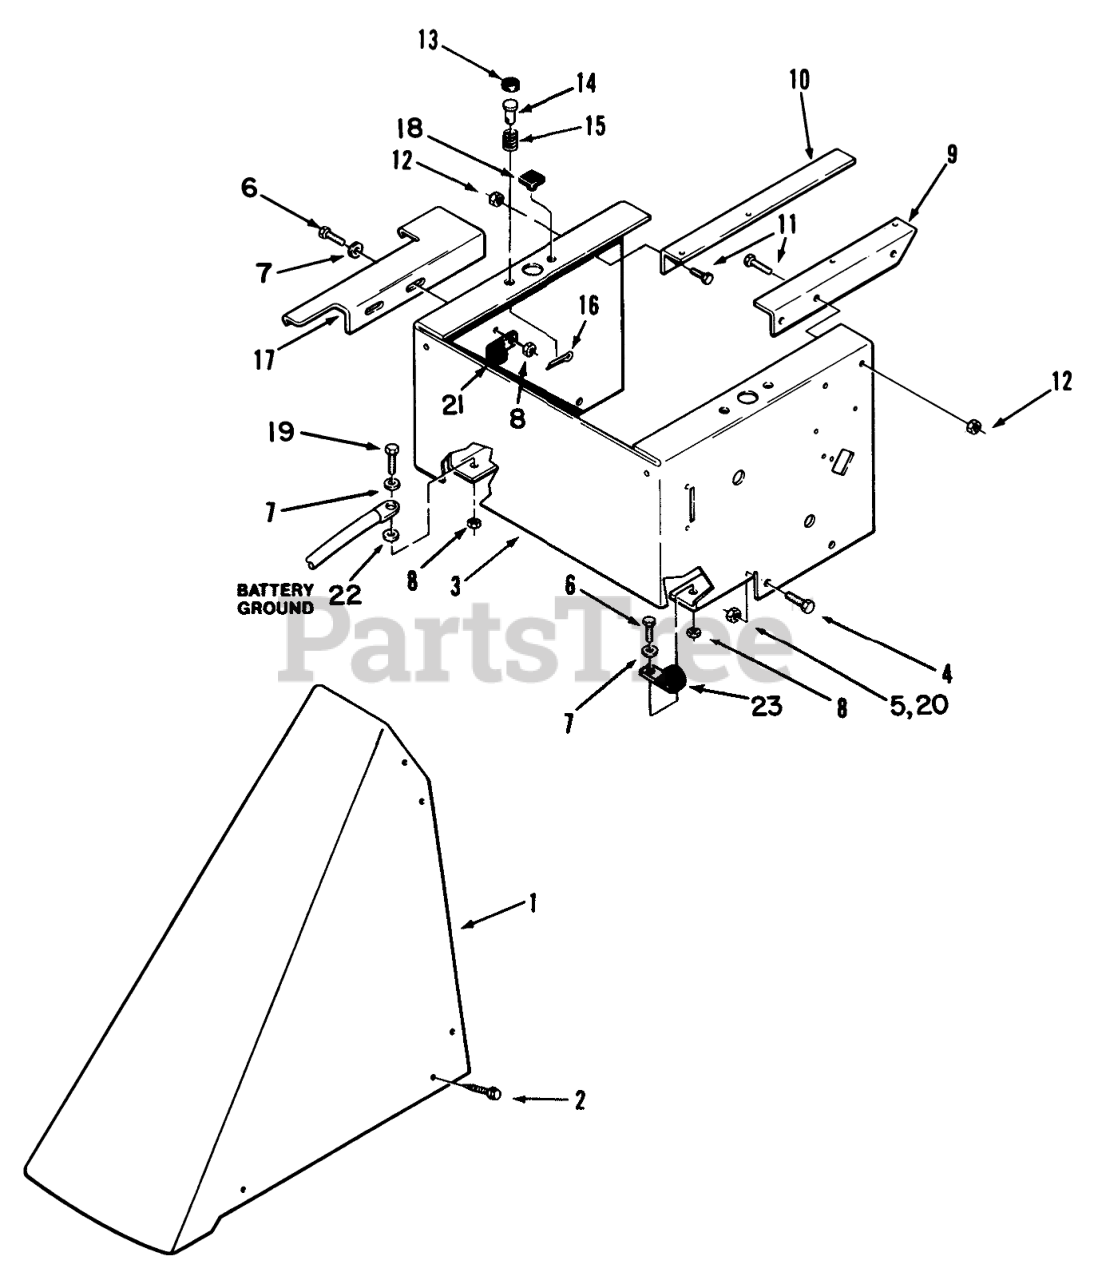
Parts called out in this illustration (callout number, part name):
1	COVER CONSOLE R
2	HEX WASHER STS
3	SUPPORT-SEAT R
4	BOLR HWH 3/8-16X7/8
5	NUT-LOCK, NI
6	SCREW-HH
7	WASHER-PLAIN
8	NUT-LOCK, NI
9	WLDMT-TANK SUPPOR R
10	WLDMT-TANK SUPPOR R
11	SCREW-HH
12	NUT-HEX
15	SPRING
16	PIN-COTTER
17	PLATE SHIFT R
18	BUMPER SJ5514 BLACK
19	SCREW-HH
20	NUT-LOCK, SIDE
21	CLIP
22	WASHER-LOCK, INTERNAL
23	J-CLIP
